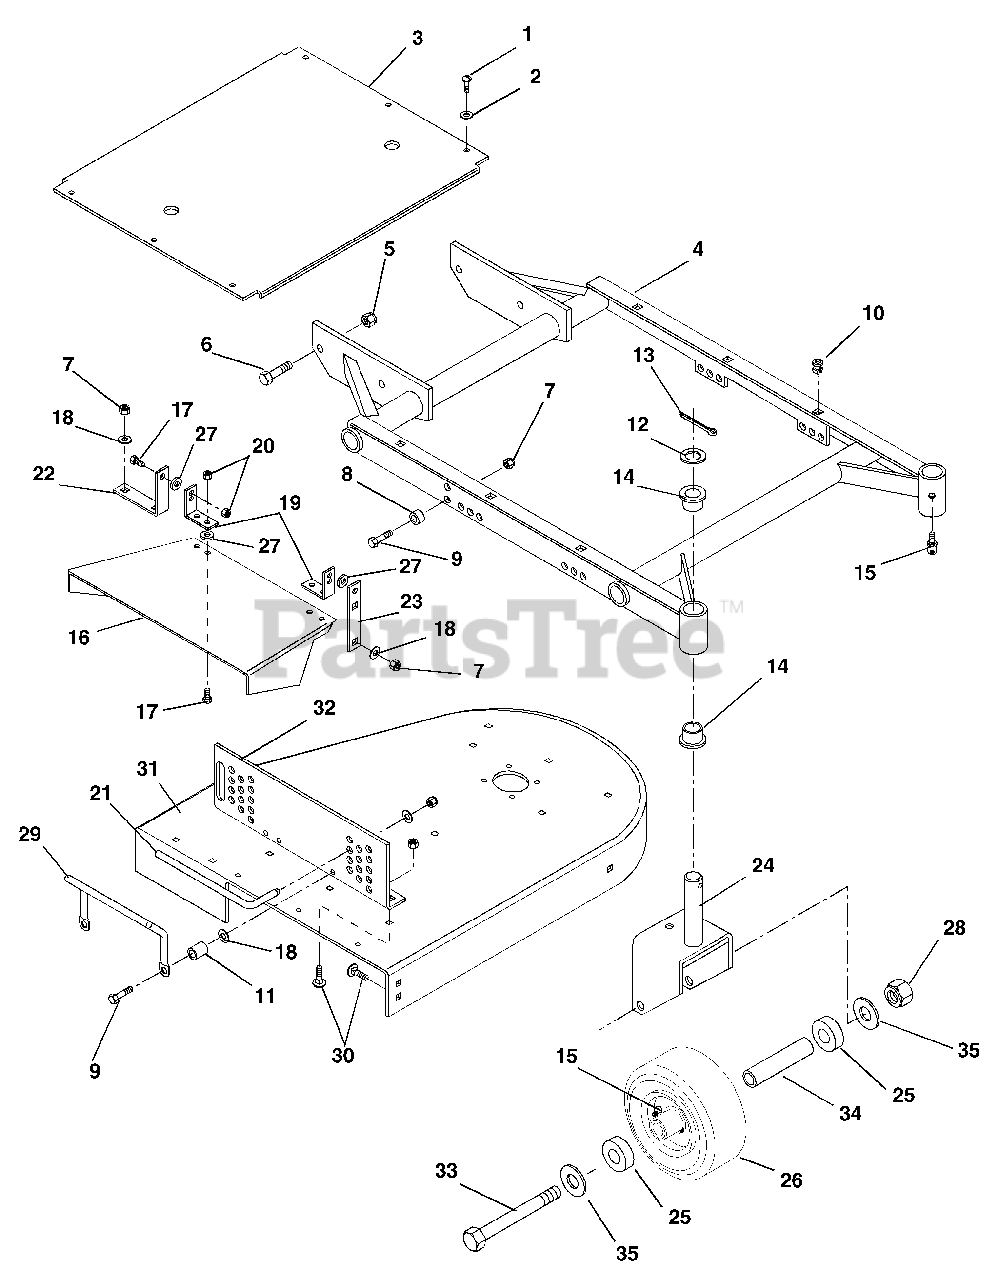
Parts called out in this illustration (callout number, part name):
1	Screw-Tapping .25-20 x .50 Hex Washer Head
2	Washer-Flat-Steel .281 x .625 x .065
3	Cover, Belt Pro Mower
4	Weldment-Mower Frame 36"
5	Nut-Locking-Center .61-11
6	Bolt-Hex .62-11 x 1.50
7	Nut-Locking-Nylon .38-16
8	Bushing .391 x .626 x .670
9	Bolt-Hex .38-16 x 1.50 Grade 5
10	Grommet, Plastic
11	Bushing
12	Washer-Hardened-Thrust 1.002 x 1.552 x .030
13	Pin-Cotter .188 x 1.50
14	Bushing-Flange 1.020 x 1.385 x .75 x 1.75
15	Fitting-Lube .25-28 x .256
16	Chute-Discharge
17	Bolt-Hex .31-18 x .75 Grade 5
18	Washer-Flat-Steel .406 x .812 x .065
19	Bracket, Discharge Chute
20	Nut-Locking-Nylon .31-18
21	Pin-Mower Locking
22	Bracket
23	Bracket
24	Weldment-Caster Fork
25	Spacer .755 x 1.25 x .37
26	Wheel 9 x 3.50
27	Washer-Flat-Rubber .375 x 1.50 x .060
28	Nut-Locking-Ctr .50-13
29	Handle
30	Bolt-Round Head Square Neck .38-16 x 1.00 Grade 5
31	Weldment-36 inch Deck
32	Bracket-Mower Side Support - Left Hand
32	Bracket-Mower Side Support - Right Hand
33	Bolt-Hex .50-13 x 5.50 Grade 5
35	Washer-Flat-Steel .754 x 1.00 x .032
